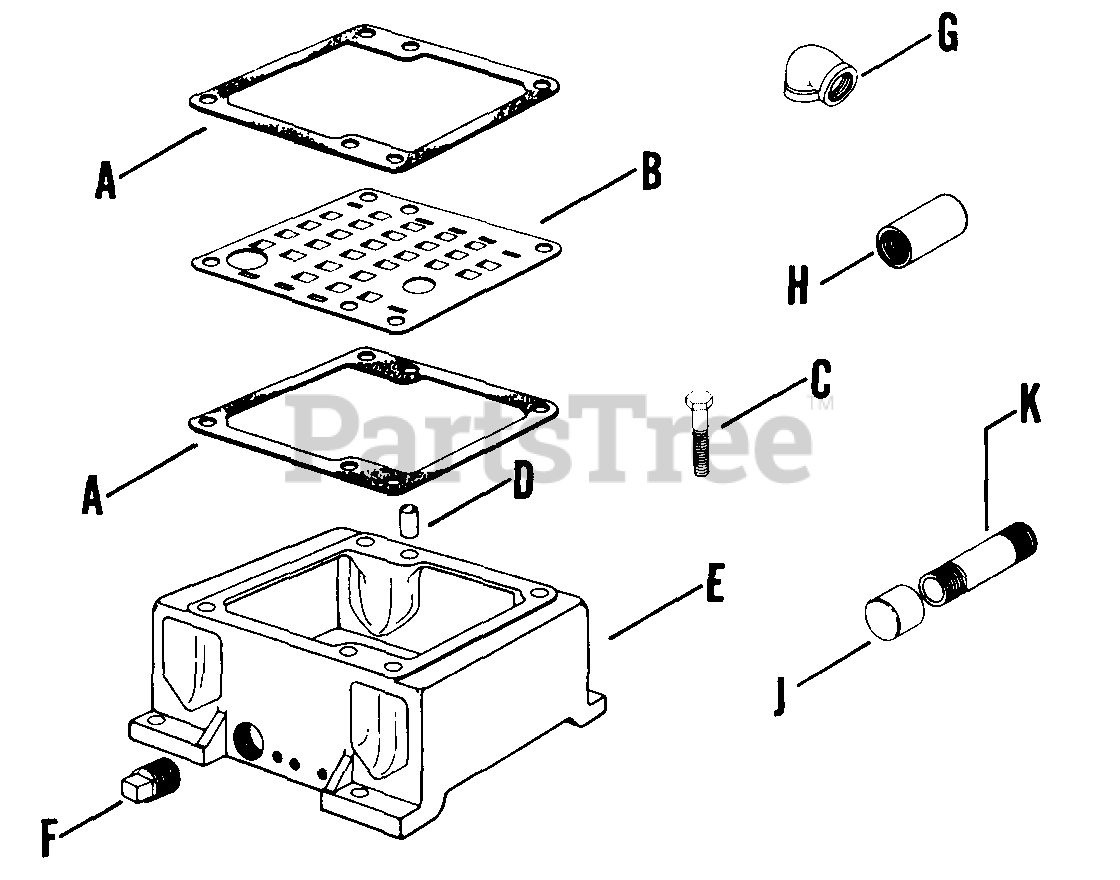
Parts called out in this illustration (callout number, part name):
B	BAFFLE - DISCONTINUED
C	SCREW - DISCONTINUED
F	PLUG,PIPE SQ HD 3/4" USE 25 139 56-S
